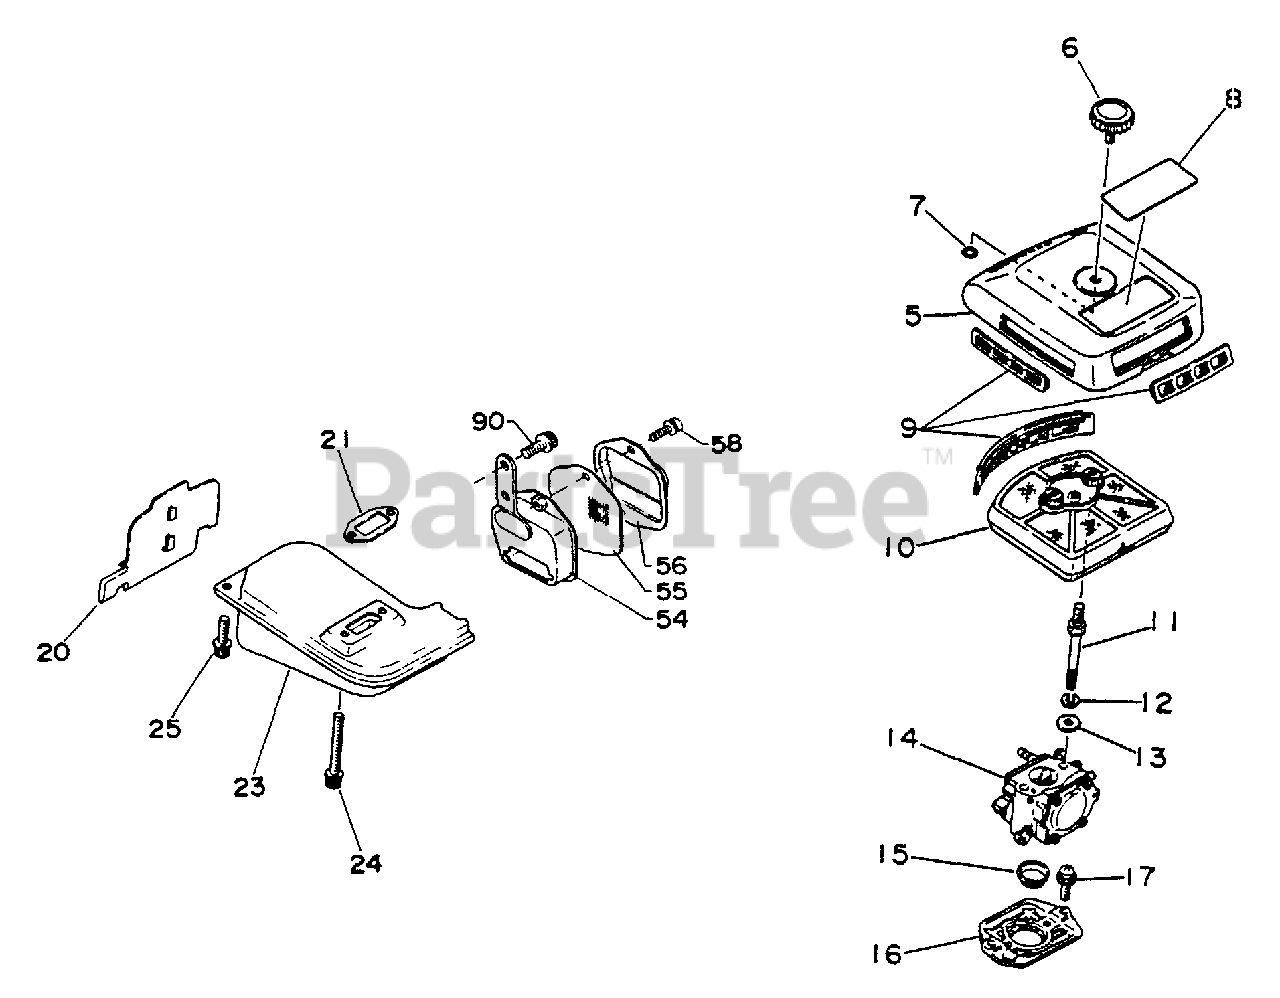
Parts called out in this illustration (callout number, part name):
5	COVER, AIR FILTER
6	THUMBSCREW
7	O-RING - 3
8	LABEL
9	DEBRIS FILTER KIT
10	FILTER, AIR
11	STUD
12	LOCKWASHER - 5
13	WASHER - 5
14	CARBURETOR HDB-17
15	SEAL
16	ADAPTOR
17	SCREW - 4X12
20	INSULATOR
21	GASKET, EXHAUST
23	MUFFLER
24	SCREW - 5X50
25	SCREW - 5X20
54	ADAPTOR
55	SCREEN, SPARK ARRESTOR
56	GUIDE, EXHAUST
58	SCREW - 4X12
90	SCREW - 5X12
